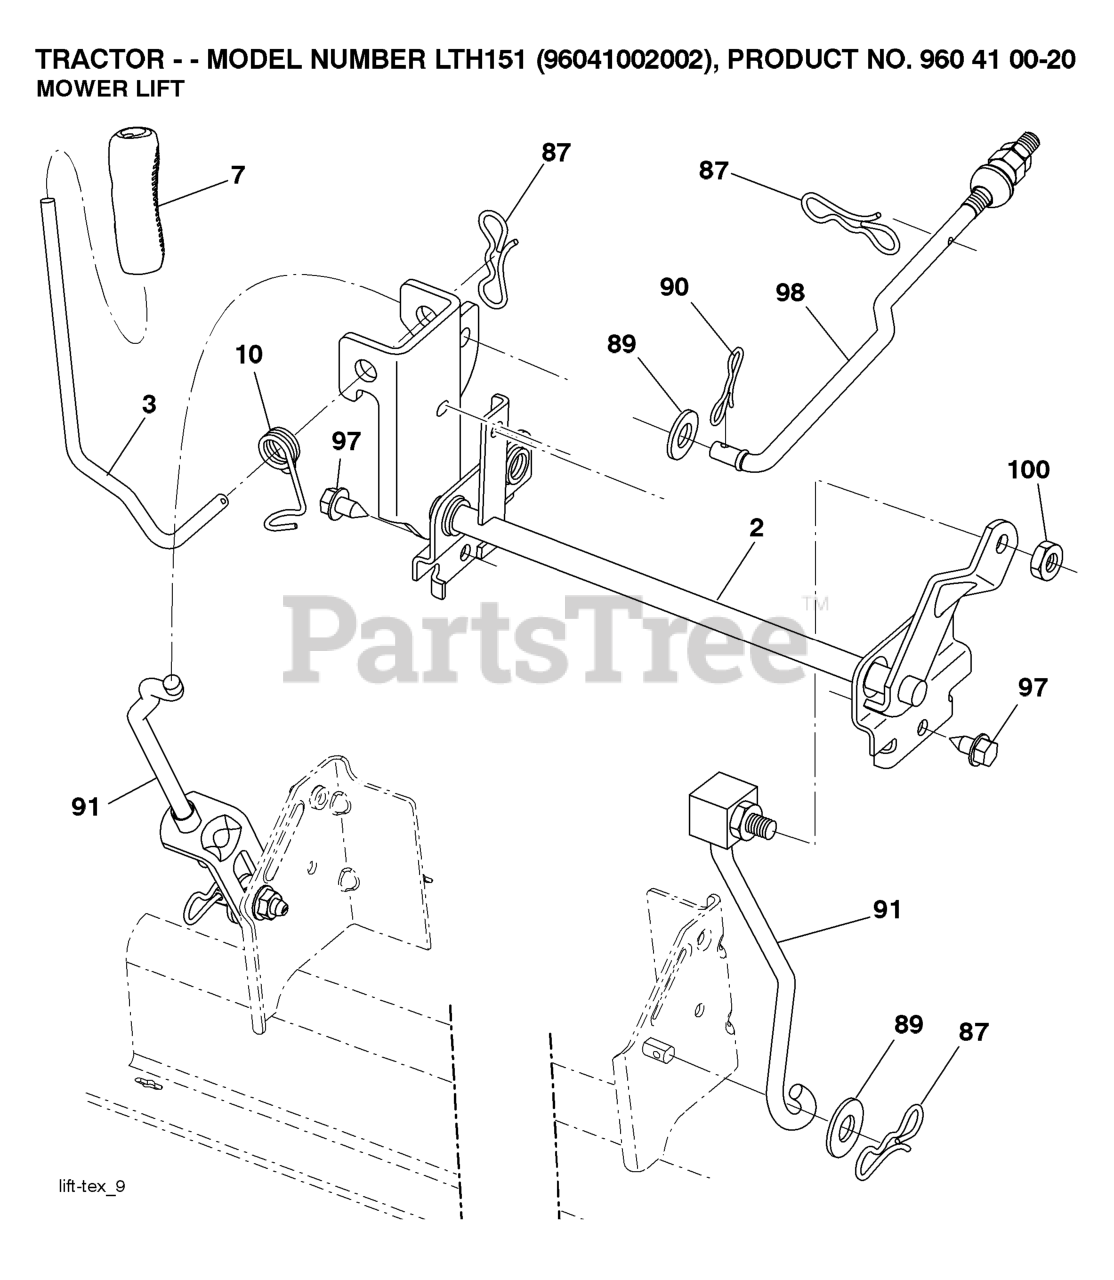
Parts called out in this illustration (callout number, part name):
2	SHAFT.ASM.LIFT.CROSS.H
3	LEVER.LIFT.HANDLE.LT
7	GRIP.HANDLE.LIFT.PVC.BLACK
10	SPRING.TORSION.LIFT.HANDLE
87	PIN.COTTER.7/16.BOW TI.
88	SPRING.LIFT.ASSIST
89	WASHER.CLEAR.ZINC
90	PIN.COTTER.5/16.BOW TI
91	LINK.ASM.LIFT.REAR
97	SCREW, 3/8-16X3/4
98	LINK.ASM.SUSP.FRONT.MW
100	LOCKNUT
